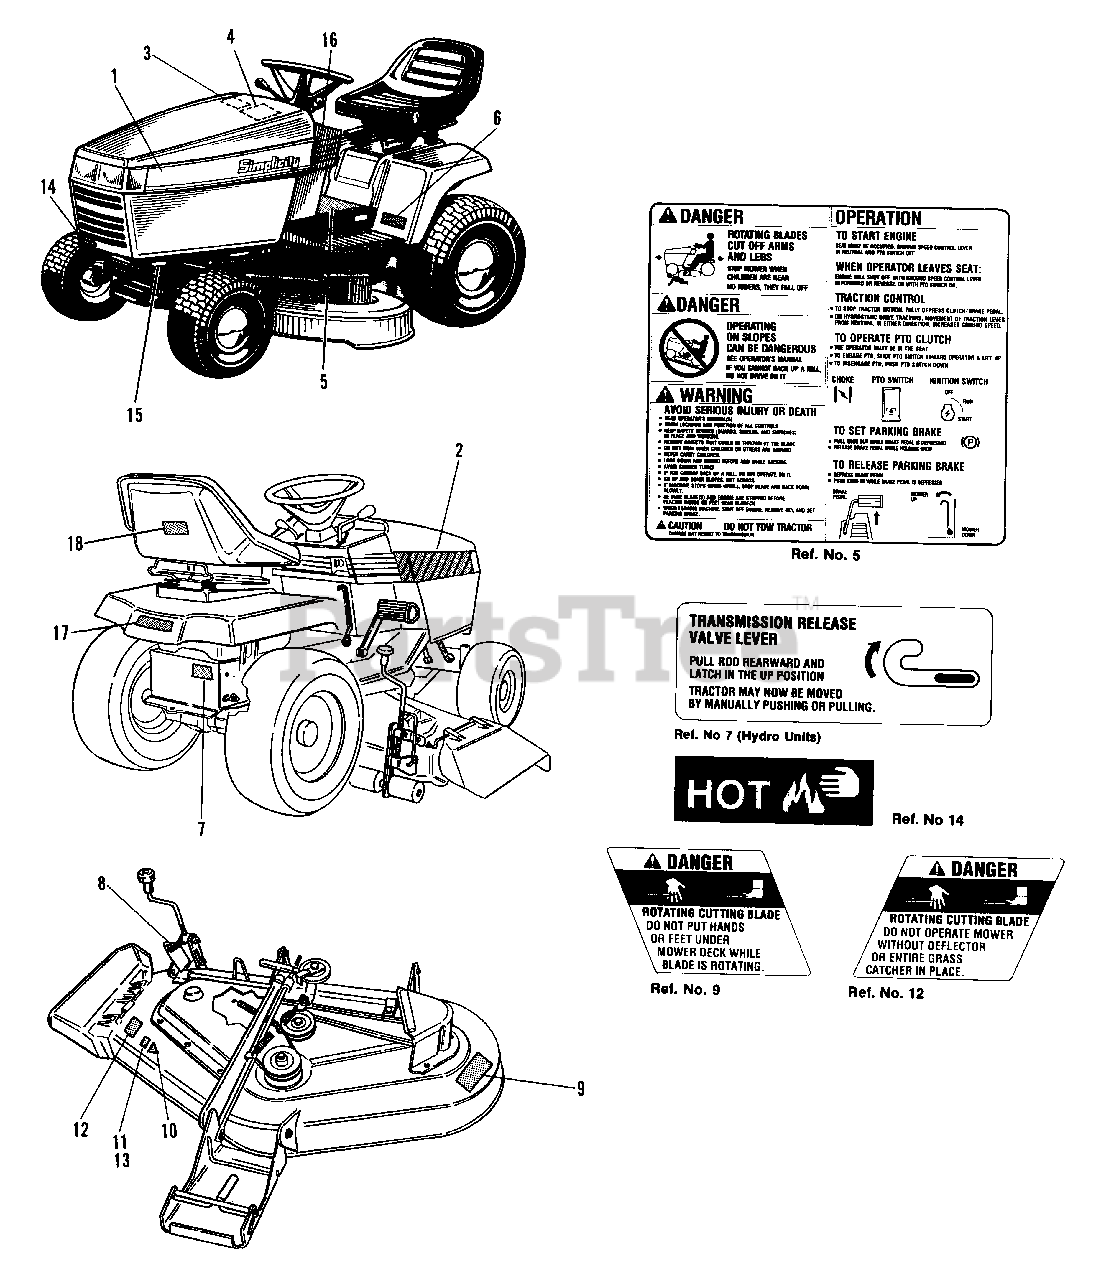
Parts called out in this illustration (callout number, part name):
1	DECAL, Hood, L.H., LTH Models
1	DECAL, Hood, L.H., Broadmoor 16H
1	DECAL, Hood, L.H., Broadmoor 14H
1	DECAL, Hood, L.H., Broadmoor 12.5H
1	DECAL, Hood, L.H., Broadmoor 12.5G
2	DECAL, Hood, R.H., LTH Models
2	DECAL, Hood, R.H., Broadmoor 16H
2	DECAL, Hood, R.H., Broadmoor 14H
2	DECAL, Hood, R.H., Broadmoor 12.5H
2	DECAL, Hood, R.H., Broadmoor 12.5G
3	DECAL, Paint (Early Models Only)
4	DECAL, Belt, Blade
5	DECAL, Operating Inst.
6	DECAL, 12.5 LTH (Early Models Only)
6	DECAL, 12.5 LTG (Early Models Only)
6	DECAL, 16 LTH (Early Models Only)
7	DECAL, Push Valve (Hydrostatic Units only)
8	DECAL, Mower Height
9	DECAL, Danger (Hand Under Deck)
10	DECAL, OPEI
11	DECAL, Cutting Width, 38"
12	DECAL, Danger (Chute in Place)
13	DECAL, Cutting Width, 44"
14	DECAL, Grille, Hot
15	I.D. PLATE
16	DECAL, Choke (Dash), 12.5 and 14 HP Kohler Only
17	DECAL, Logo (Simplicity)
18	DECAL, USA Logo
18	DECAL, Battery
